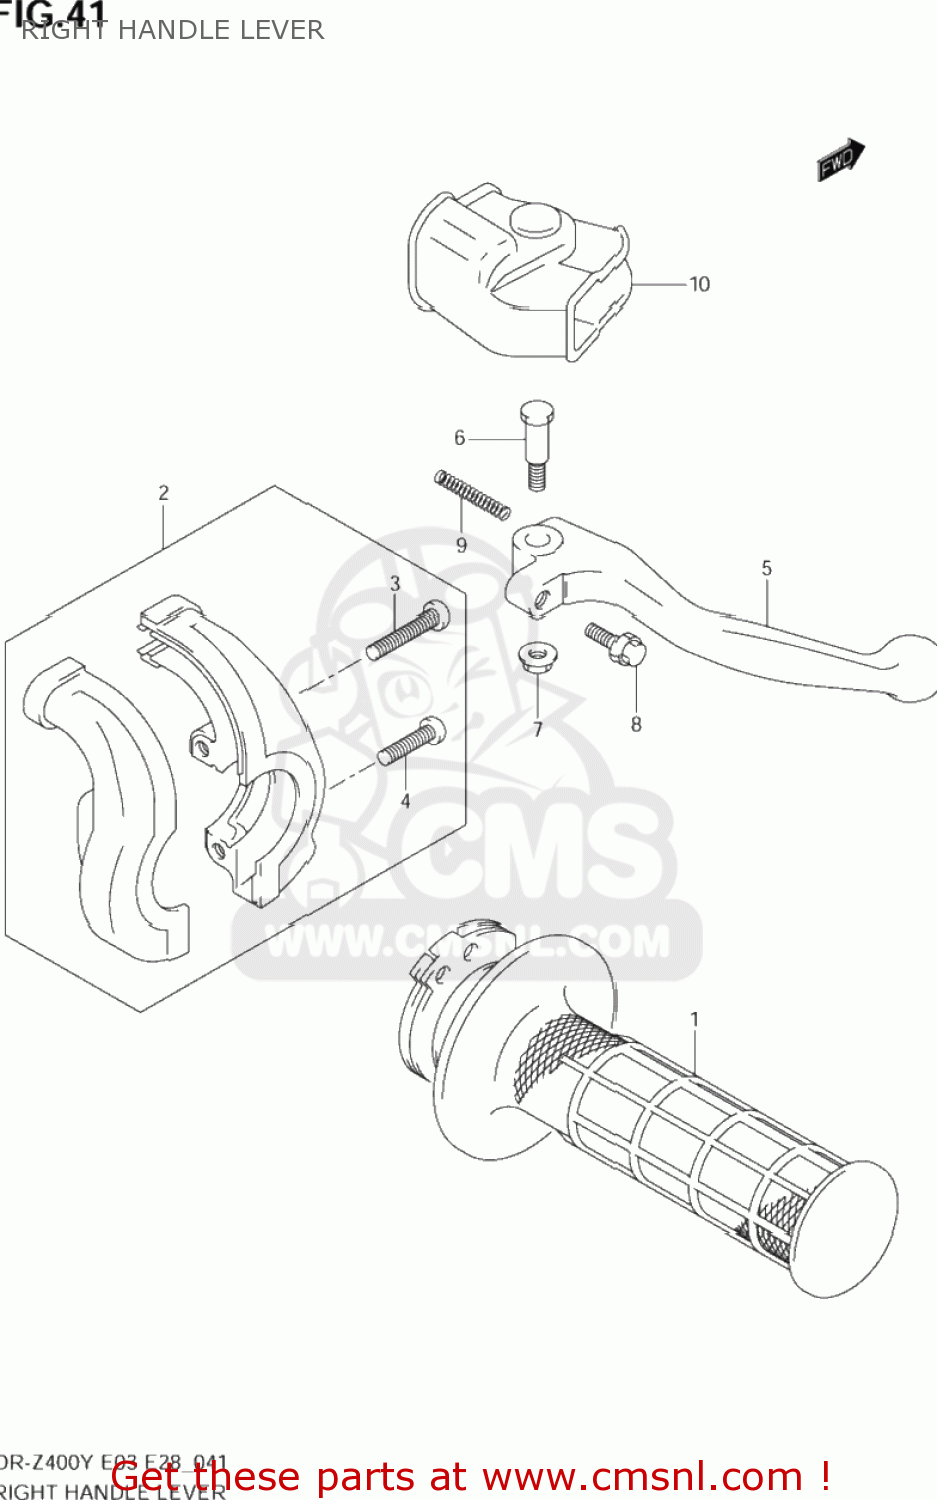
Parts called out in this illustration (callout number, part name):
1	GRIP,THROTTLE
2	CASE ASSY,THROTTLE
3	SCREW(5X25)
4	SCREW
5	LEVER,BRAKE
6	BOLT,BRAKE LEVER
7	NUT
8	BOLT,ADJUSTER
9	SPRING,RETURN
10	COVER,BRAKE LEVER
